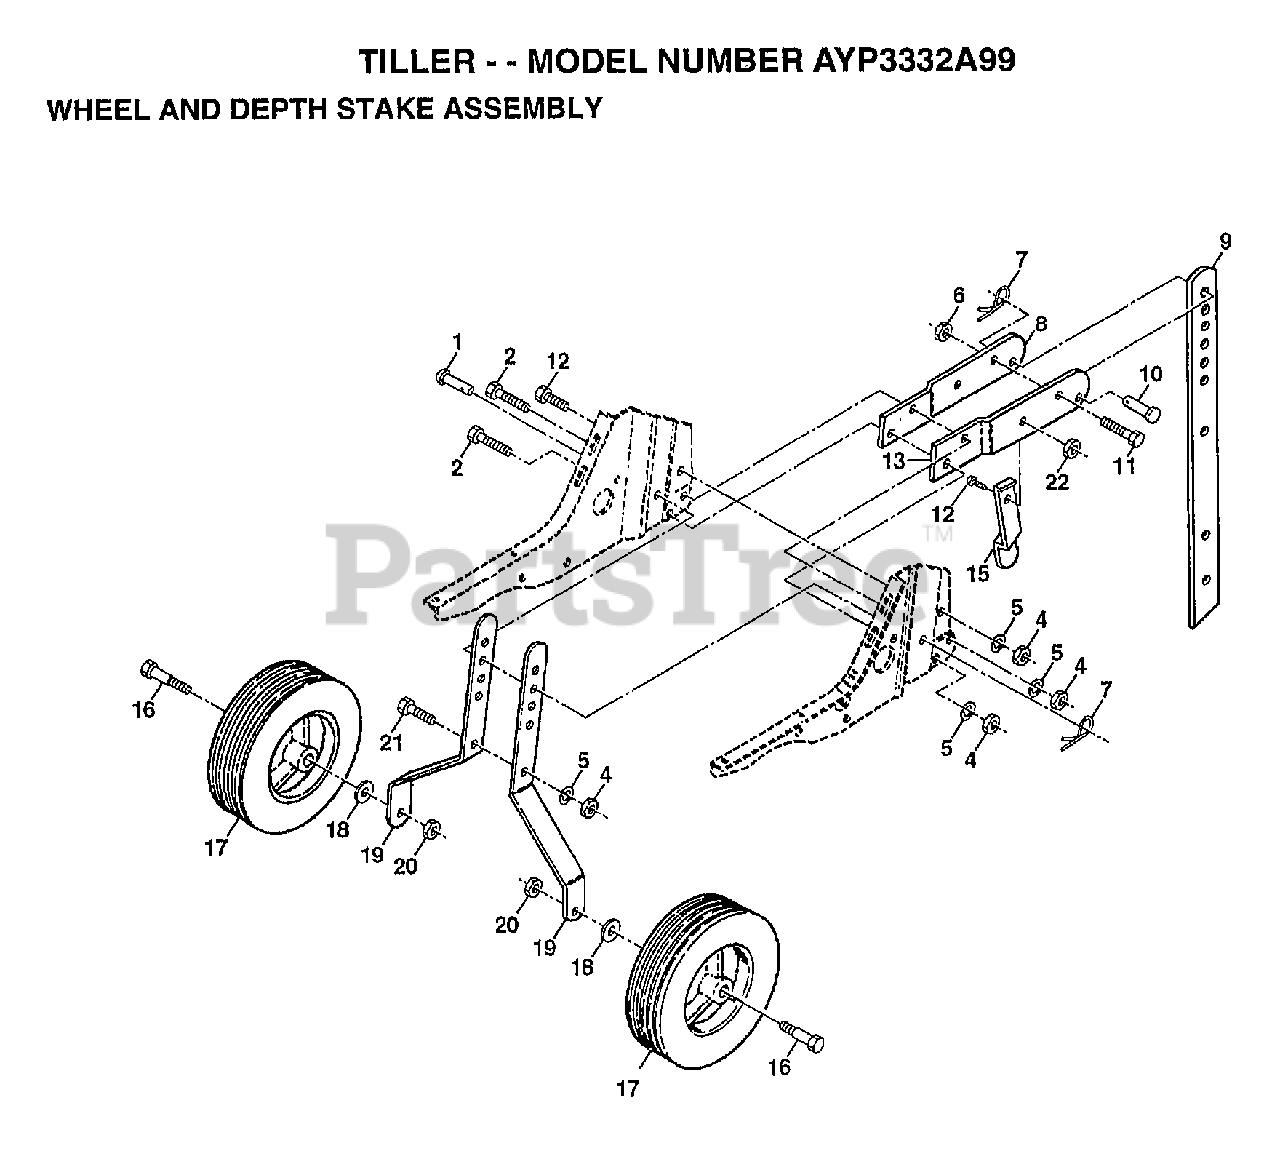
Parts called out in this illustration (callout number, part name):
1	DRILLED RIVET RT
4	NUT.HEX.5/16-18
5	LOCKWASHER
6	NUT
7	SPRING.RETAINER
8	STAKE.SUPT.TILLER
10	DRILLED RIVET RT
11	BOLT.HEX.5/16-1.5
12	BOLT
15	STAKE SPRING TI
16	BOLT SHOULDER
18	WASHER
22	NUT
